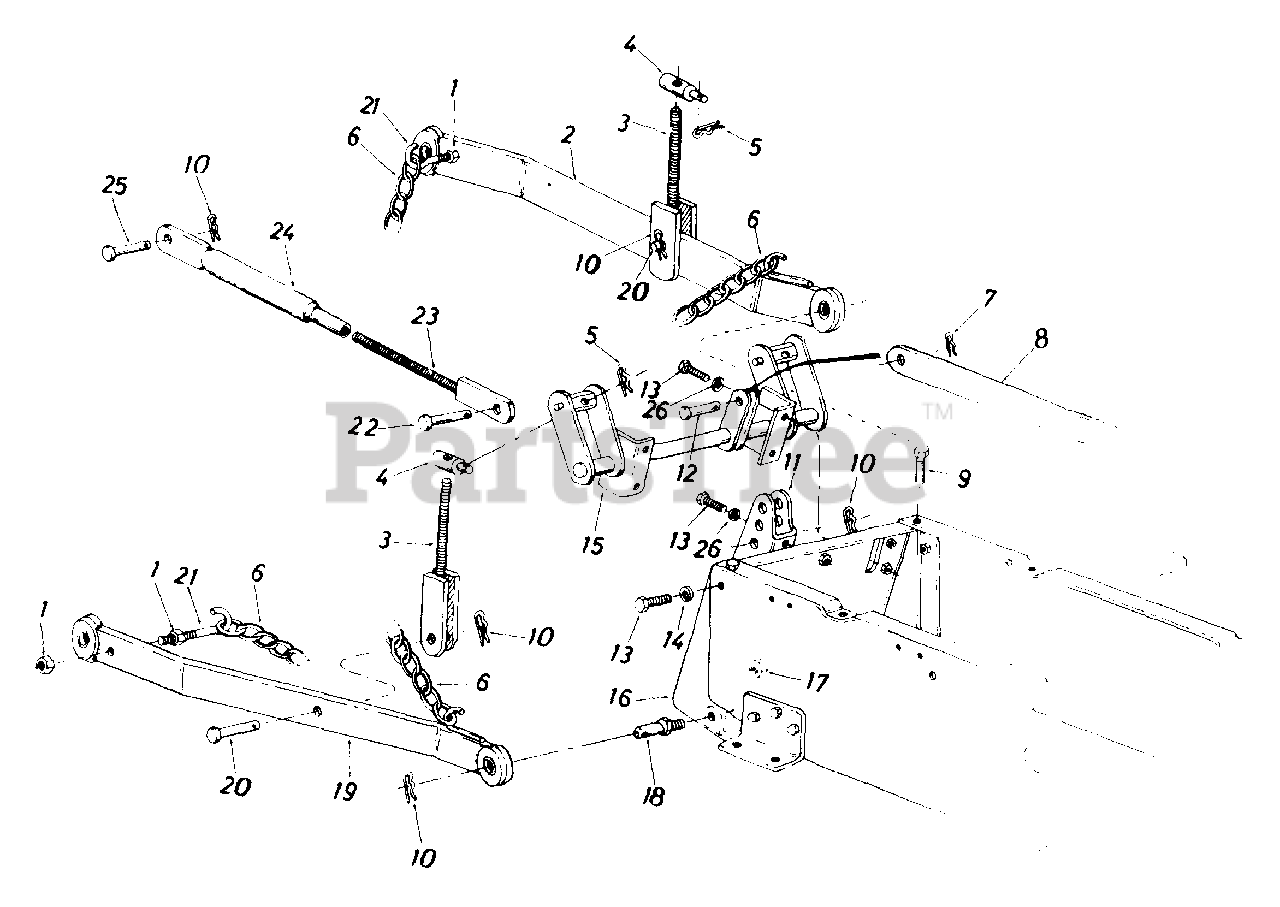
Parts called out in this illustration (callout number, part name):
1	Hex Cent. L-Nut 7/16-14 Thd.
2	Draft Bar Ass'y. - L.H.
3	Clevis Screw Ass'y.
5	Hitch Pin Clip
6	Chain - 20 Links
7	Cotter Pin 1/8" Dia. x 1.25" Lg.
10	Hairpin Cotter
13	Hex Scr. 3/8-16 x .75" Lg.
14	L-Wash. 3/8" Scr. - H.D.
18	Link Clevis Pin
19	Draft Bar Ass'y. - R.H.
20	Clevis Pin .63" Dia. x 3.66" Lg.
21	Hitch Chain Hook
22	Clevis Pin .63" Dia. x 2.4" Lg.
23	Clevis Screw
25	Clevis Pin .63" Dia. x 2.4" Lg.
26	L-Wash. 3/8" Scr. - H.D.
